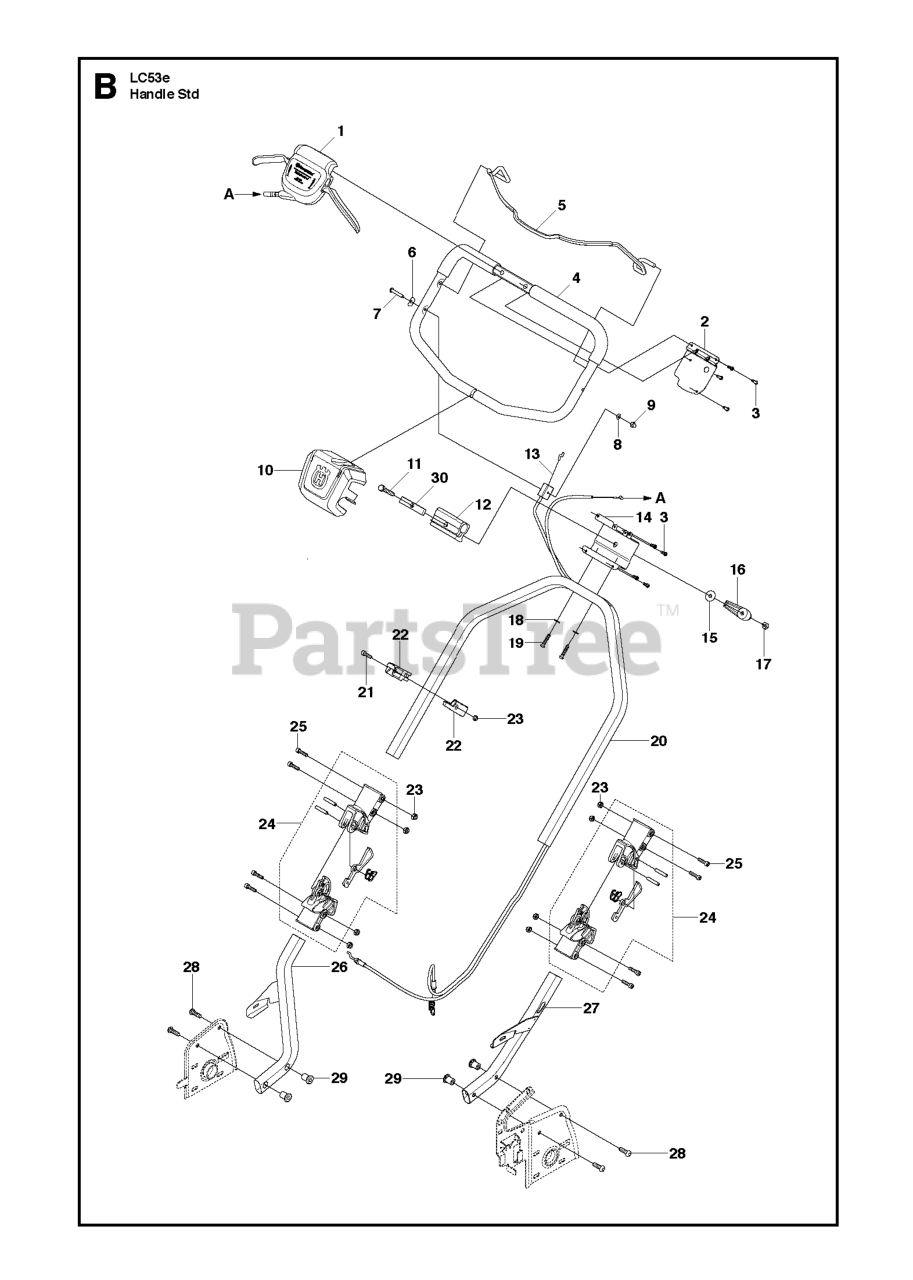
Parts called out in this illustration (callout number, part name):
8	WASHER - M6
15	WASHER - 25X8.5X2.3
21	SCREW MC6S 6X20
25	REPL BY 725 53 74-55
